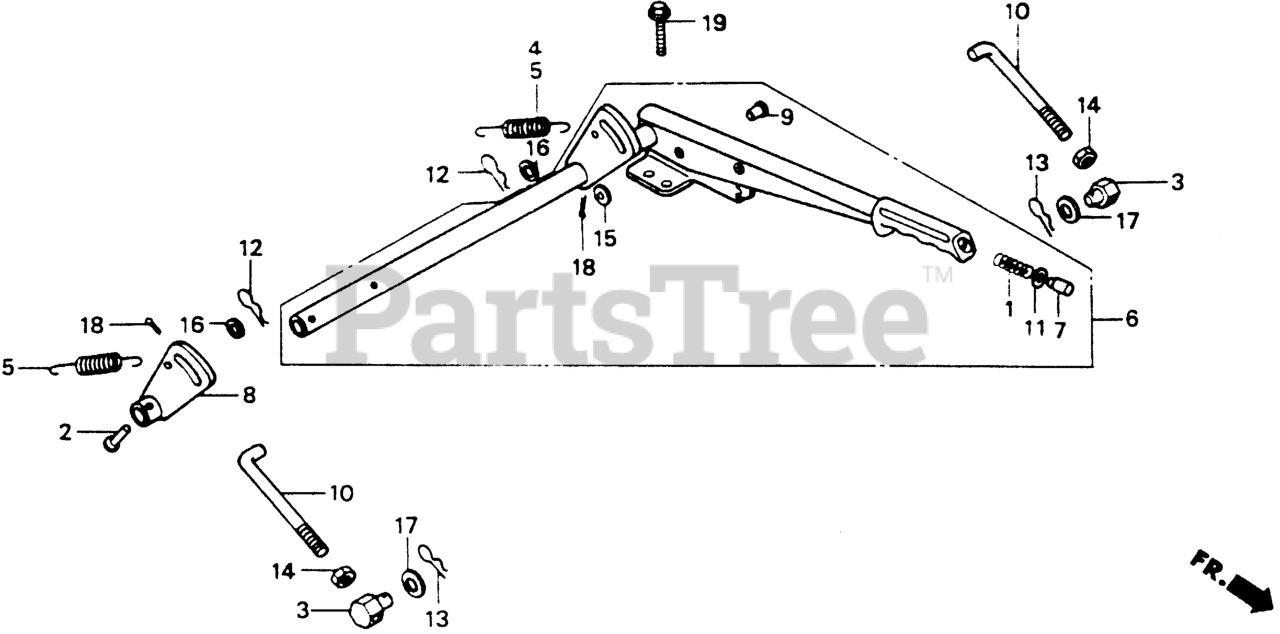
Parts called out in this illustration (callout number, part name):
1	SPRING, PUSH ROD
2	PIN (7X32.5)
3	PIN, FR. LINK ADJUSTING
4	SPRING, DECK LIFT
6	LEVER ASSY., HEIGHT ADJUSTING
6	LEVER ASSY., HEIGHT ADJUSTING (NOT AVAILABLE)
7	GRIP KIT, DECK ADJUST
7	KNOB, PUSH ROD
9	PIN, HEIGHT ADJUSTING LEVER STOPPER
10	BAR, ADJUSTING
12	PIN, LOCK (2.3MM)
13	PIN, LOCK (14MM)
14	NUT, HEX. (12MM)
15	WASHER, PLAIN (10MM)
16	WASHER, PLAIN (12MM)
17	WASHER, PLAIN (14MM)
18	PIN, COTTER (2.0X15)
19	BOLT, FLANGE (8X16)
